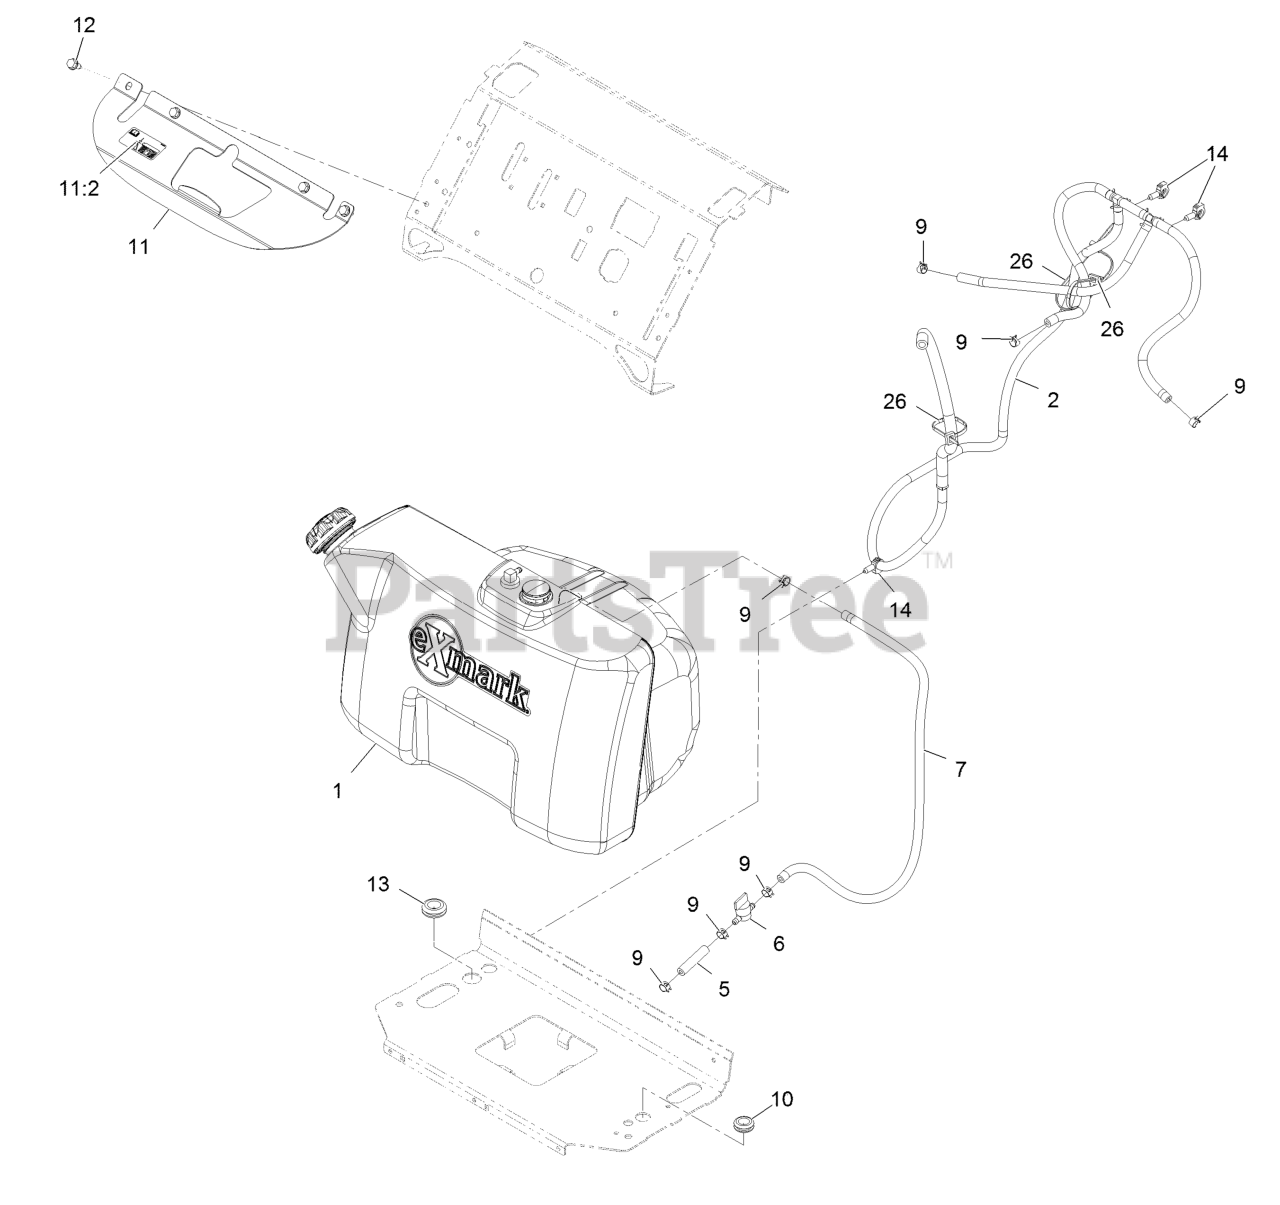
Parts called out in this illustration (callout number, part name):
1	Tank ASM-
2	Vent ASM
5	Hose-Fuel
6	Valve-Fuel
7	Hose-Fuel Line 32"
9	Clamp-Hose
10	Grommet
11	Bracket-Tank
11:2	Decal-Fill, Fuel
12	Screw-HWH 5/16-18 X 3/4 Tf
13	Grommet
14	Clip-Harness
26	Tie-Cable
